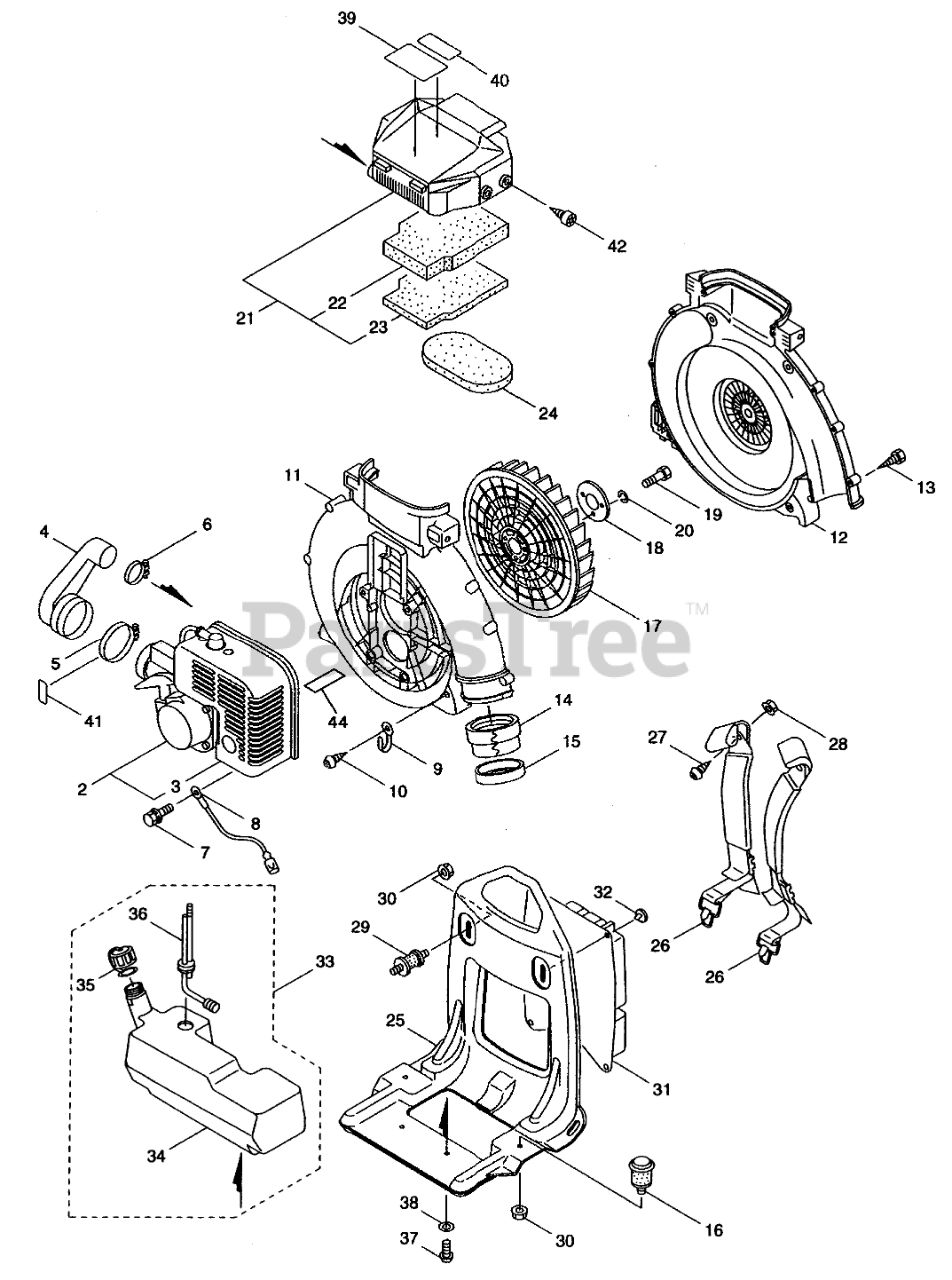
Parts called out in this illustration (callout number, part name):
1	Blower Assembly
2	Engine (Incl. Ref. # 3)
3	Shroud
4	Pipe-Inlet
8	EARTH CORD
9	CLAMP
10	TAPPING SCREW
11	Case-Fan (E)
12	FAN CASE (S)
13	Screw-Tapping
14	Collar
15	Rubber Band
16	BUFFER
18	PLATE
20	SPRING WASHER
21	Air Cleaner Assembly (Incl. Ref. # 22,23)
22	ELEMENT
24	PACKING
25	KNAPSACK FRAME
26	Band-Knapsack
27	SCREW
29	BUFFER
31	Cushion Pad
32	FASTNER
33	Fuel Tank Assembly
34	Tank-Fuel
35	CAP ASSY
36	FILTER ASSY
37	SCREW
38	WASHER
39	LABEL
40	LABEL
41	DECAL-CHOKE
42	TAPPING SCREW
43	DECAL - HOT SERFACE
